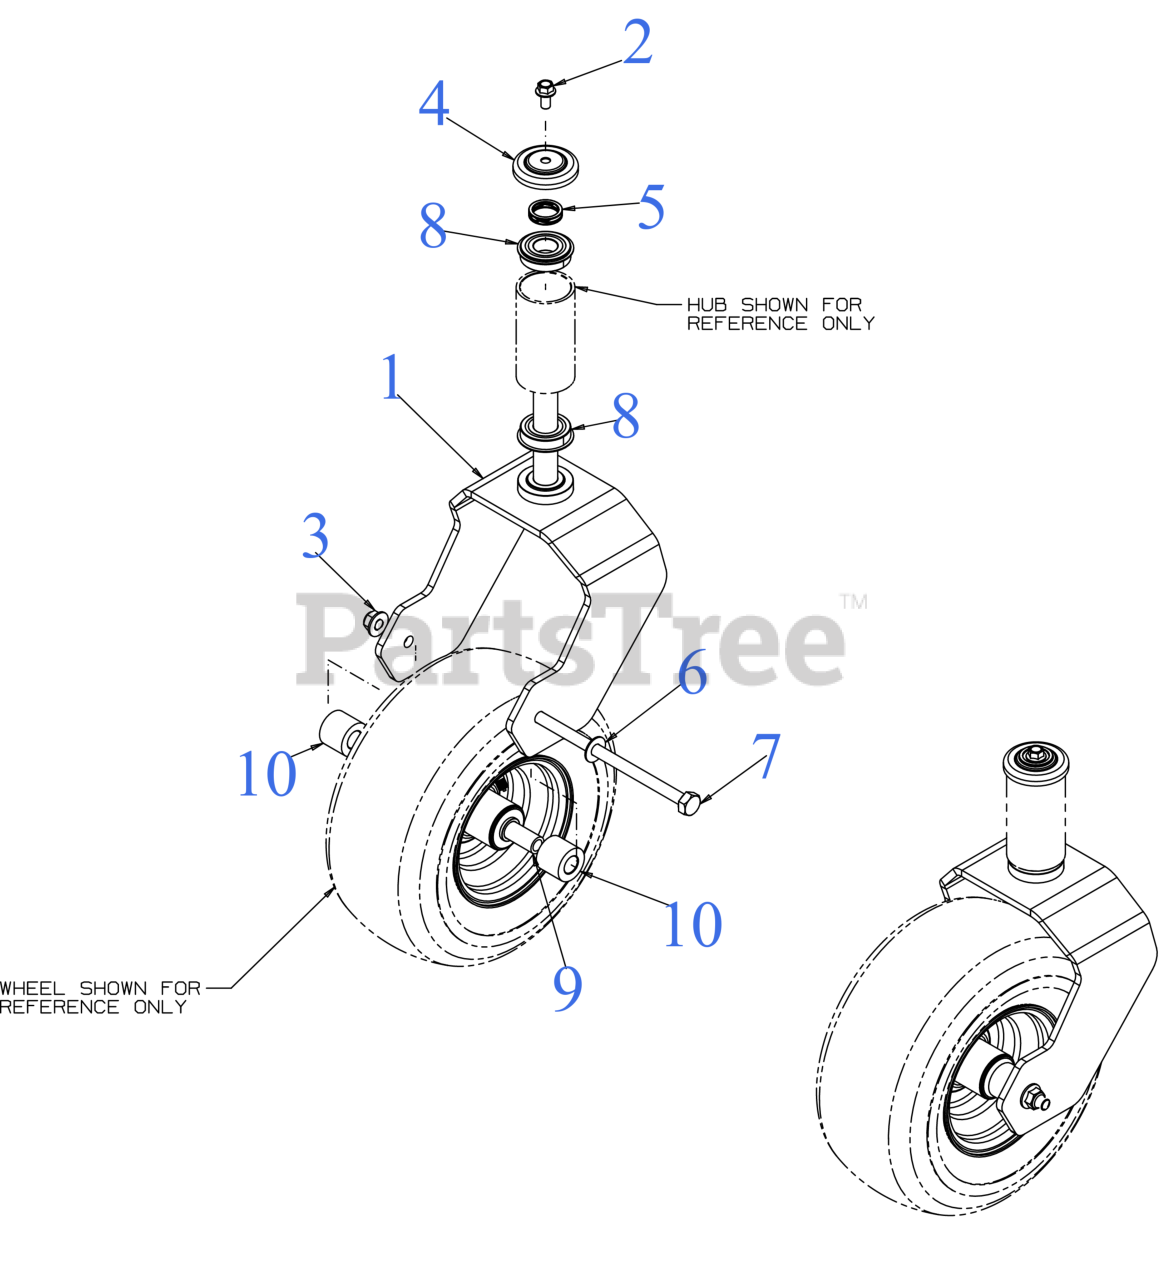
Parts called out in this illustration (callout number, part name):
1	CASTER WHEEL YOKE
2	BOLT - 3/8-16:.75:GR5:PATCH LOCK
5	WAVE WASHER
6	FLAT WASHER
7	SCREW-1/2-13X8.5 GR5 FLG RZF-SX
8	BALL BEARING 25X52X15
9	CASTER AXLE SPACER
10	CASTER WHEEL SPACER
